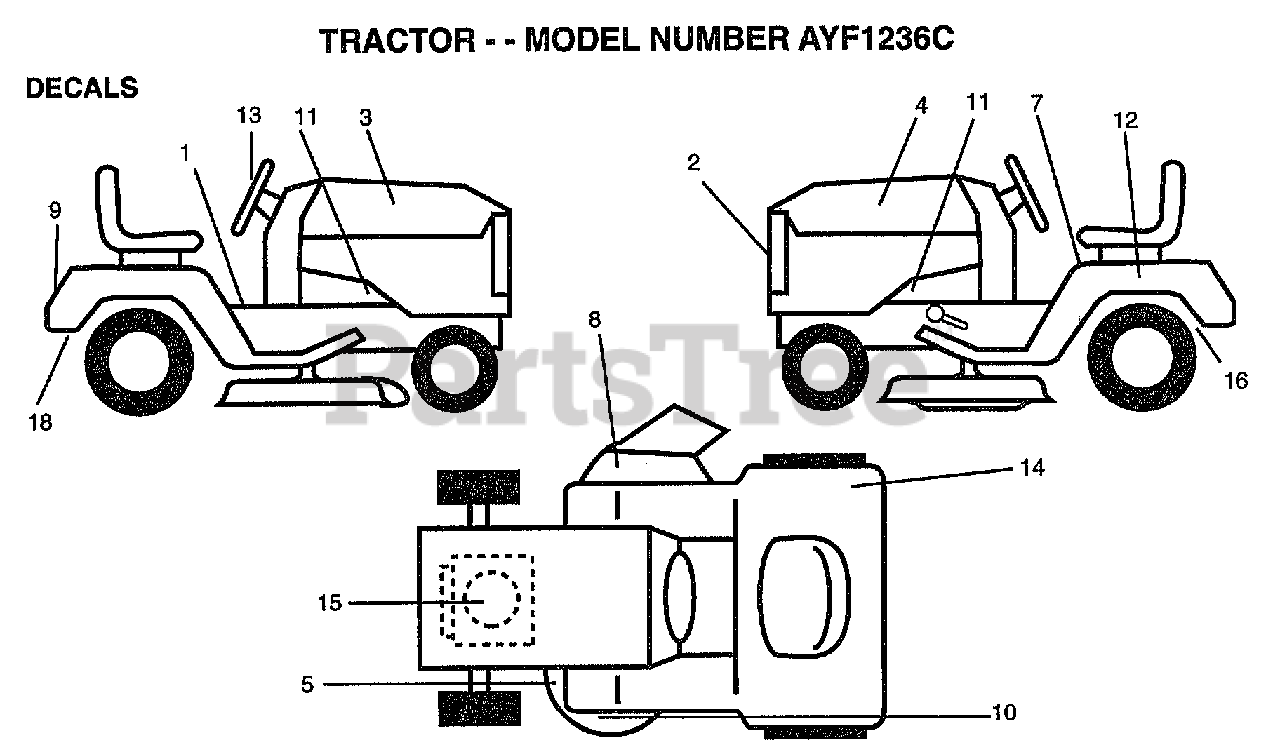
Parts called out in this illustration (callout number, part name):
1	DECAL CLUTCH/BRAK
2	"DECAL,LIGHT BOX"
3	DECAL.HOOD.RH
4	DECAL.HOOD.LH
5	DECAL.V.BELT
7	DECAL.READ.O.MANU
8	DECAL.DANGER.CUTF
9	DECAL.FENDER
10	DECAL DECK WIZ +
11	"DECAL CHASSIS,HOT"
12	DECAL.BATRY.3-3908
13	DECAL.INSERT.STR
16	DECAL.DRAWBAR.LDL
18	DECAL.EURO.ST.CE.
